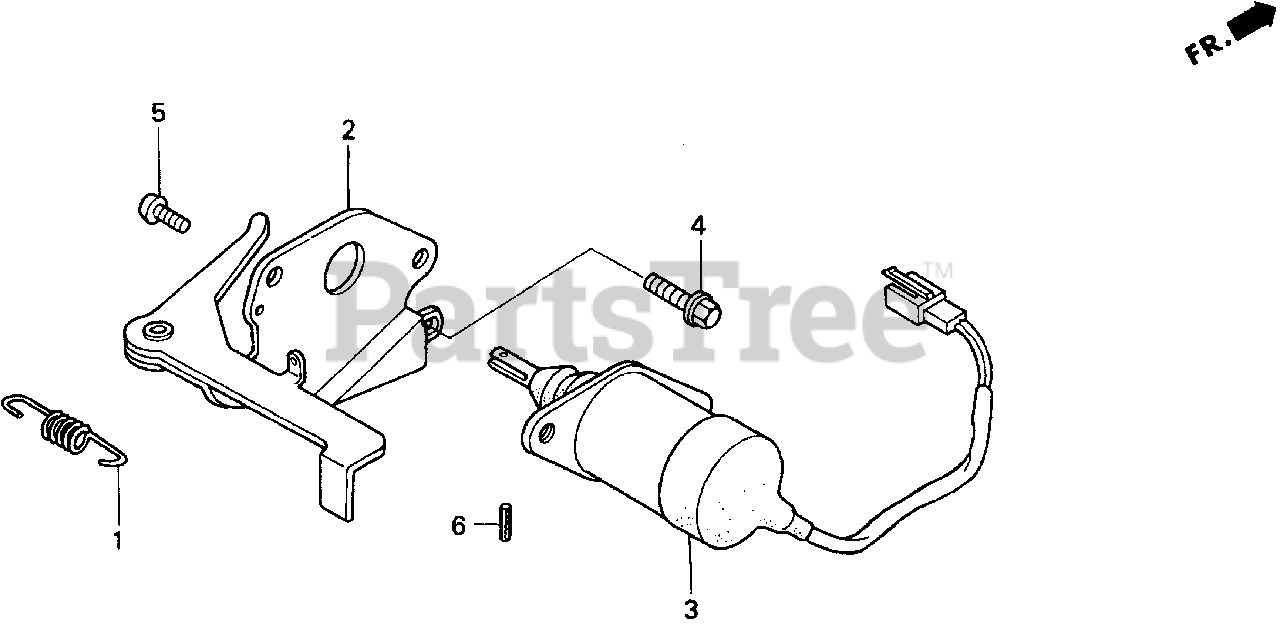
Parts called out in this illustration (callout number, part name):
1	SPRING, CHOKE RETURN
2	LEVER, THROTTLE
3	SOLENOID ASSY.
4	BOLT, FLANGE (6X12) (CT200)
5	SCREW, PAN (5X8)
6	PIN, SPRING (2.5X16)
